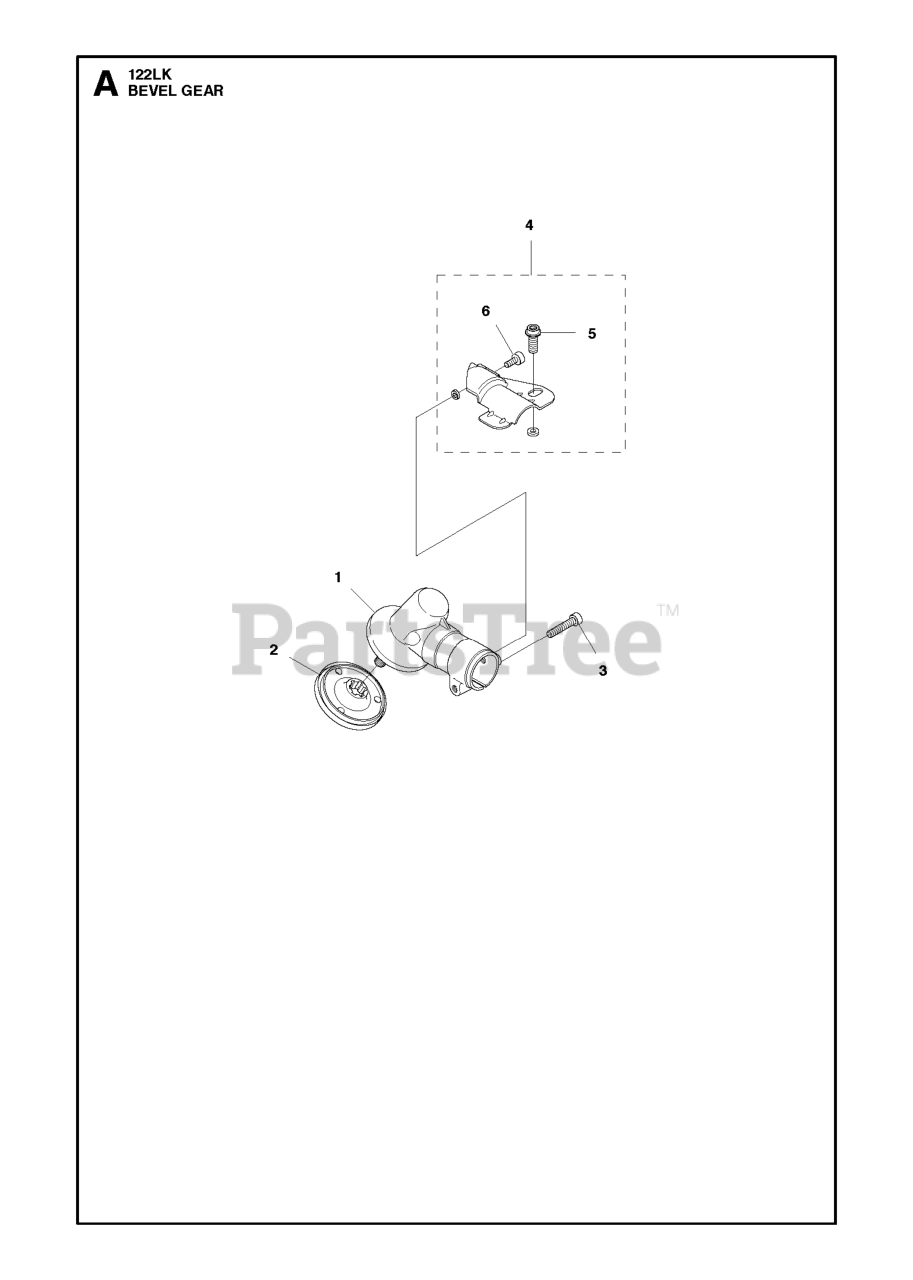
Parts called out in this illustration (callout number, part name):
1	ASSY GEARBOX
2	DRIVE DISC
3	SCREW - CARB. ADAPTOR
4	BRACKET ASSY
5	SCREW ITXSCFM
